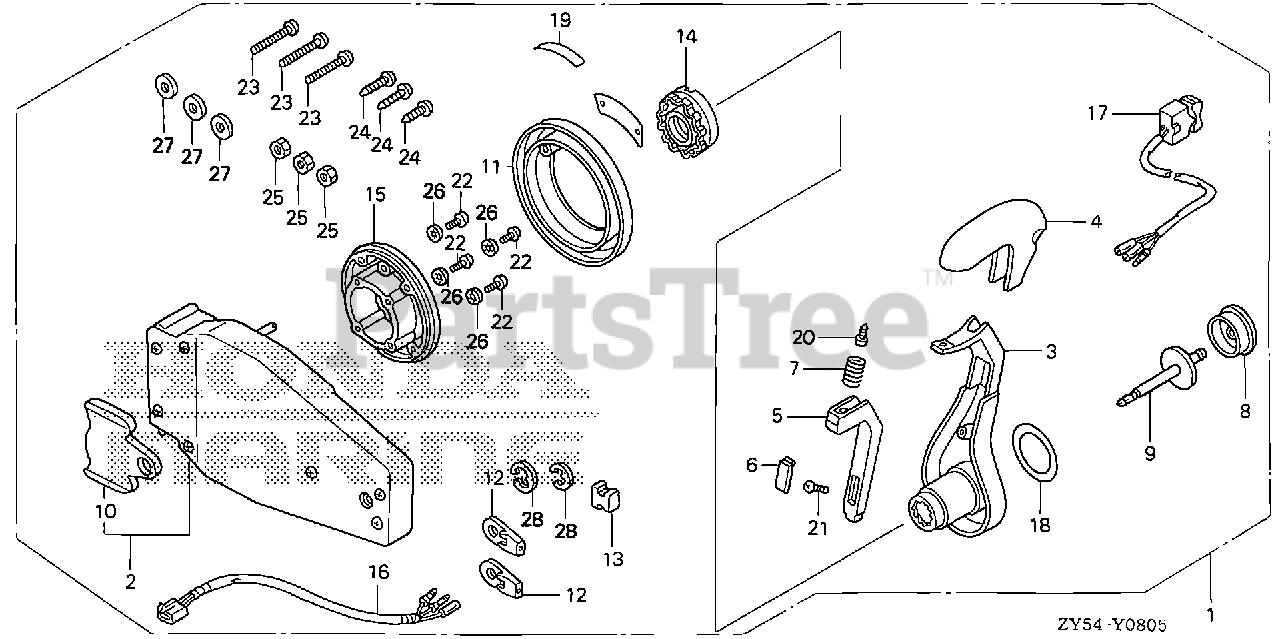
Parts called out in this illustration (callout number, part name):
1	BOX KIT, REMOTE CONTROL (FLUSH MOUNT)(L)
2	HOUSING ASSY., L. (INNER) (FLUSH MOUNT)
3	HANDLE, REMOTE CONTROL
4	COVER, GRIP
5	ARM, NEUTRAL LOCK
6	COVER, LOCK ARM
7	SPRING, NEUTRAL LOCK ARM
8	BUTTON, THROTTLE
9	SHAFT, THROTTLE BUTTON
10	PLATE, DWELL
11	COVER ASSY.
12	TERMINAL, CABLE
13	SPACER, CABLE CLAMP
14	HOLDER, NEUTRAL LOCK
15	BASE
16	SUB-HARNESS ASSY., POWER TRIM-TILT (C)
17	SWITCH ASSY., POWER TRIM-TILT (C)
18	MARK, HANDLE FLUSH MOUNT
19	MARK, FLUSH MOUNT
20	SCREW, PAN (5X16)
21	SCREW, TRUSS (4X12)
22	SCREW, PAN (5X30)
23	SCREW, PAN (6X35)
24	SCREW, TAPPING (6X30)
25	NUT, HEX. (6MM)
26	WASHER, LOCK (5MM)
27	WASHER, PLAIN (6MM)
28	E-RING (6MM)
